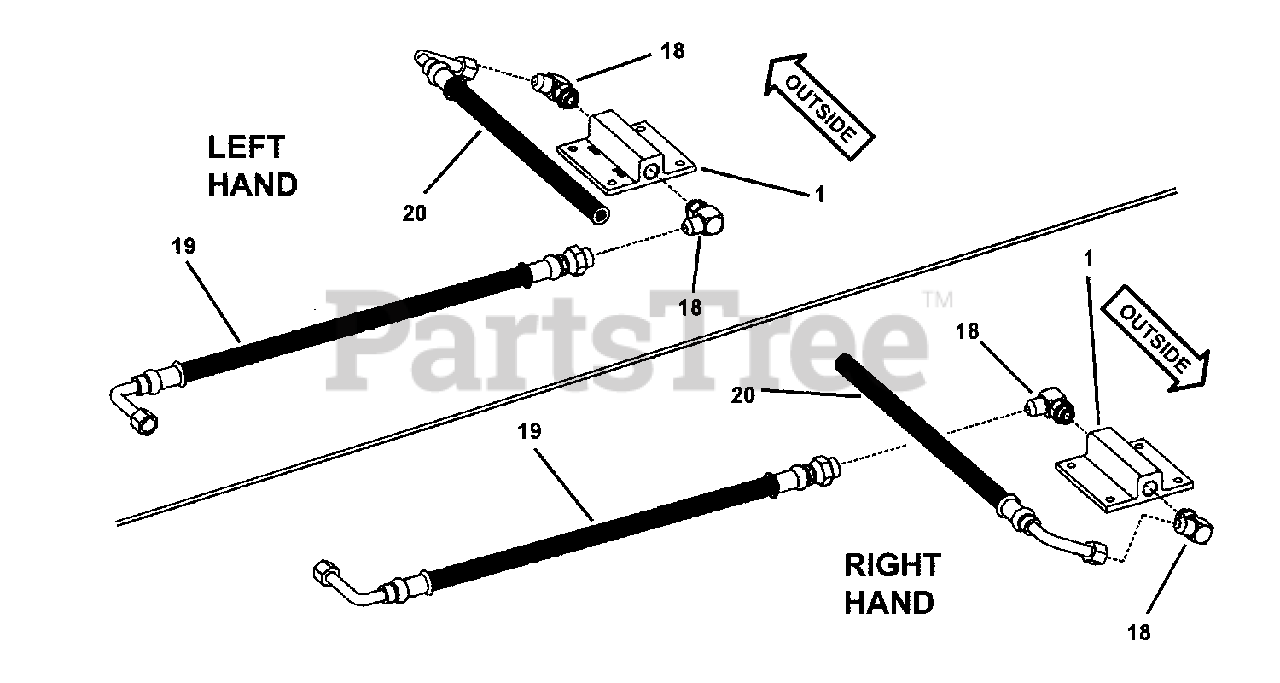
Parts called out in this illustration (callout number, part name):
1	MOUNT, Oil Filter
18	CONNECTOR, 90 Degree Hydraulic (Parker # 8 C5OLO-S)
19	HOSE, 18-1/2" (Parker R836BKJCJ9090808-18.5)
20	HOSE, 12-1/4" (Parker # R836BKJ9NR080008-12.5)
